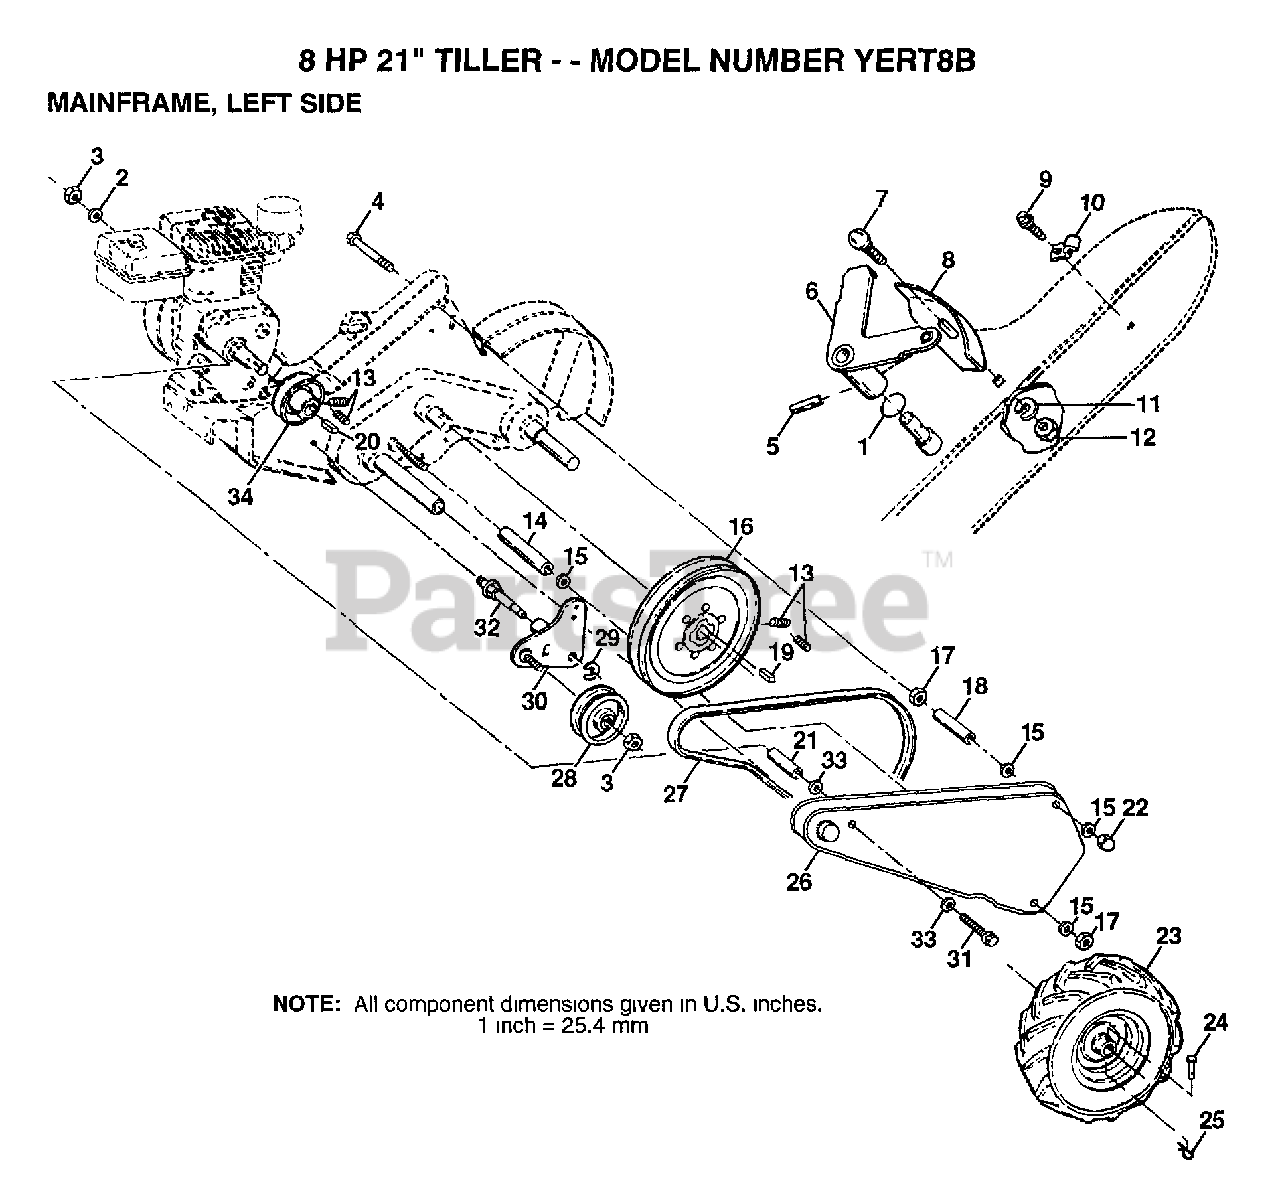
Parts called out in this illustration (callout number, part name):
1	O-RING TI
2	LOCKWASHER
3	NUT.HEX.3/8-16UNC
4	BOLT TI
6	LEVER.ASM.SHIFT
7	BOLT
8	PANEL TI
10	CONDIUT CLIP T
11	LOCKWASHER
13	SET SCREW
14	SPACER TI
15	WASHER
16	"SHEAVE 10"" CRT"
17	NUT.HEX.5/16-18
18	SPACER TI
19	KEY T
20	KEY TI
21	SPACER.SPLIT
22	NUT TI
23	TIRE TI
24	RIVET.PAN HD.1.75
25	SPRING.RETAINER
26	GUARD BELT RED
27	BELT.DRIVE
29	KLIP RING
31	BOLT1/2-20UNF2.75
32	SHAFT.IDLER
34	SHEAVE CRT
